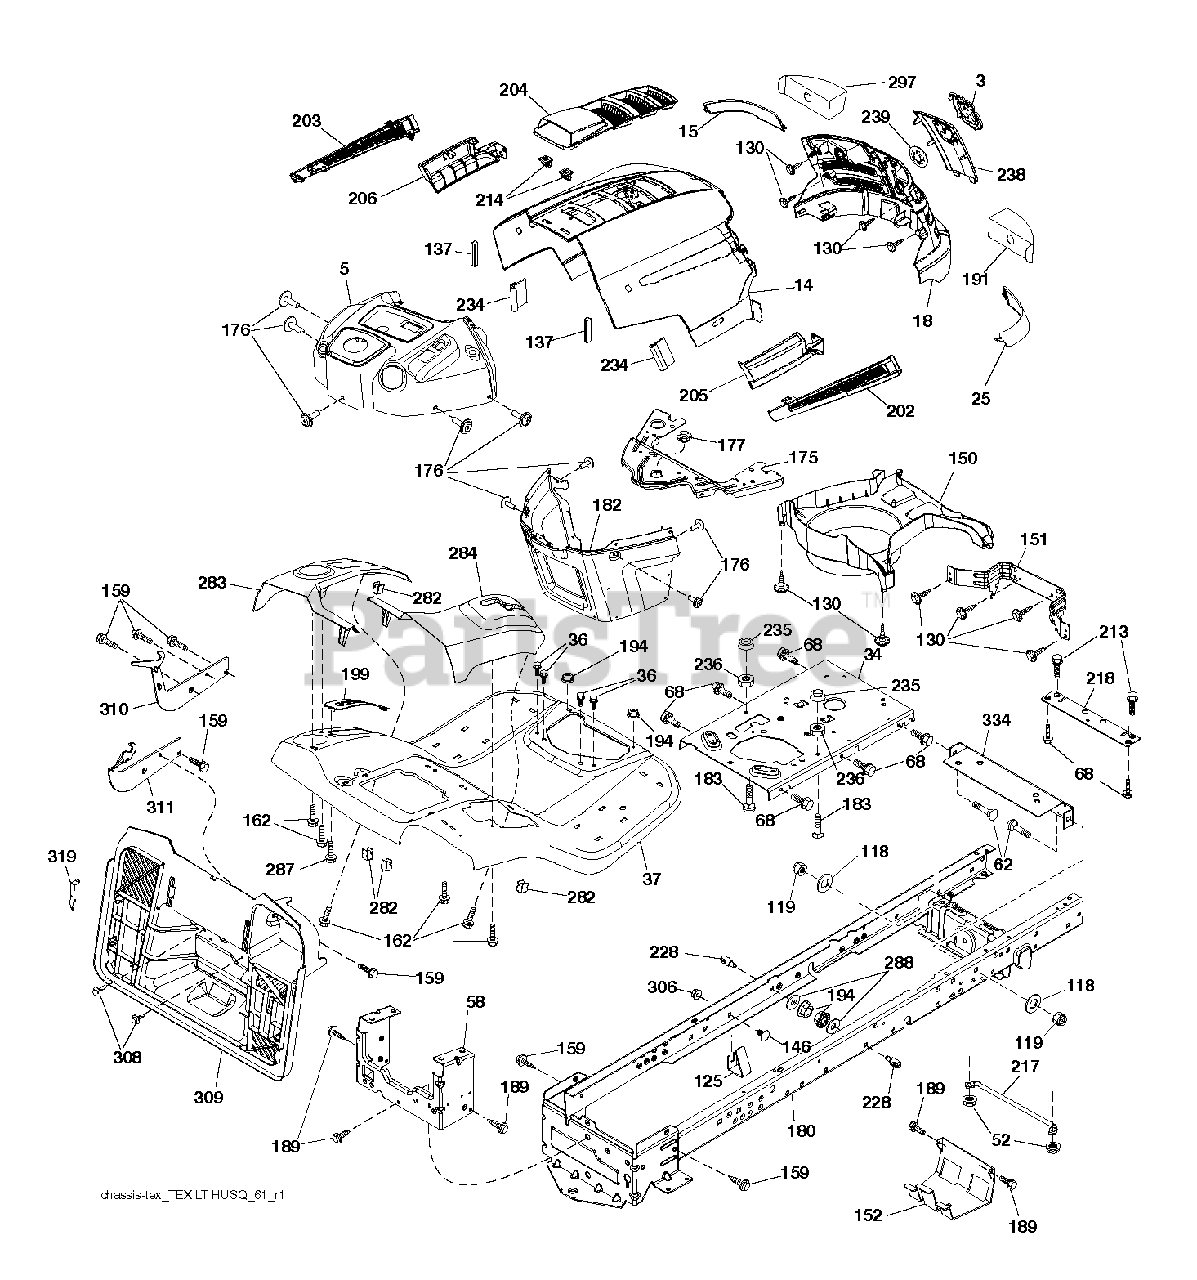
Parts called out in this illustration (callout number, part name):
3	LOGO.HUSQ.GT.LT.CROWN.H
5	SUBASM.DASH.UPPER.HLT.498
14	HOOD.HUSQVARNA.LT.ORANGE
15	LENS.HUSQVARNA LT.RH
18	GRILLE.SVC.HUSQVARNA.GREY
25	LENS.HUSQVARNA LT.RH
34	PLATE.ENGINE.10GA.CRD.GENII
36	SCREW 5/16"
37	FENDER.TEX.SRD.CRD.BASE
52	LOCKNUT
58	DRAWBAR UPPER 2PC SMALL FENDER
62	BOLT D
68	SCREW LT
118	WASHER
125	CLIP.FUEL.LINE
130	SCREW.#10 X 0.750.BOS
137	BUMPER DASH
146	BOLT.RDHD.SHT.SQNK.3/8-16X5/8
151	BRACKET PIVOT
152	SHIELD.BROWNING.W/TEX
159	SCREW, 3/8-16X3/4
162	SCREW.HI-LO.CONSOLE
175	CROSSMEMBER
176	SCREW.#10-24X5/8.RN.QU
177	BUSHING STEERING
180	CHASSIS.WLDMNT.14GA.2PC.18".TI
182	DASH.LOWER.PREDATOR LT
183	BOLT.5/16-18X1-1/4 FULL THD
189	SCREW
191	INSERT.REFLECTIVE.RH.
194	NUT LOCK HEX FLANGE 5/16-18
199	PLATE DECK LIFT
202	VENT.SIDE.HUSQVARNA.LT.RT
203	VENT.SIDE.HUSQVARNA.LT.LFT
204	SUBASM.TOP.VENT.HUSQ.LT
205	SKIRT.SIDE.HUSQVARNA.LT.RT
206	SKIRT.SIDE.HUSQVARNA.LT.LEFT
213	BOLT
214	CLIP.RETAINER.TINNER.
217	ROD.PIVOT.HOOD
218	X-PIECE.HOOD.STOP.NON/
228	STUD.FASTNER.W/ANTI-ROTATE
234	BUMPER.HOOD.TEX.HUSQVARNA
235	SPACER FENDER
236	NUT.CENTERLOCK.5/16-
238	TRIM.HUSQ LT.668
282	CLIP.RETAINER.CONSOLE.LT.HUSQ
283	CONSL.DECKLIFT.LH.SRD.TEX.CRD
284	CONSL.SHFT.PEDAL.RH.SRD.TEXCRD
287	SCREW 1/4X20
288	WASHER
297	INSERT REFLECTIVE
306	NUT LOCK FLG 3/8-16 UNC
308	BOLT, 5/16-18 X 1 3/4
309	BACKPLATE.BAGGER.V2.SRD
310	LH.ADJUST.HANGER.BRACKET.ASM
311	RH.ADJUST.HANGER.BRACKET.ASM
319	BRACKET.ACTUATOR.BAGGER.SRD
334	BRACKET.ENGINE
